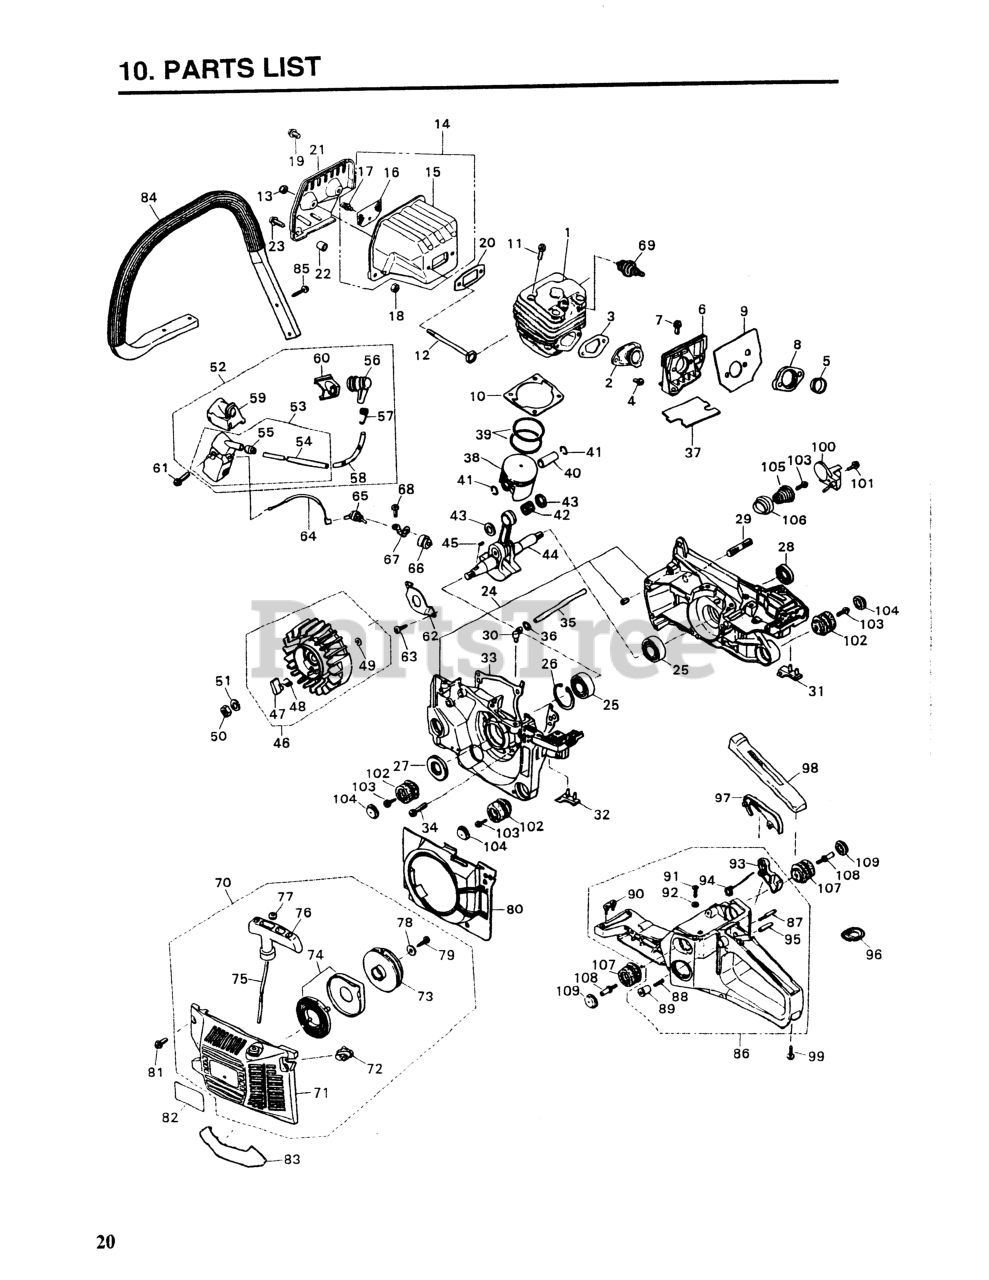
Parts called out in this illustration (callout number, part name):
2	PIPE, INLET
4	SCREW
5	GUIDE
7	SCREW (REPLACES 2616-24320)
12	BOLT
13	NUT, MUFFLER (RPLS 3356-15230
16	ARRESTER, SPARK
18	NUT, M5 X 4
19	SCREW
20	GASKET
21	COVER
26	RING, SNAP, M35 X 1.5
27	SEAL, OIL
28	SEAL, OIL
29	STUD (RPLS 0205-50825)
31	STOPPER, REAR (RPLS 2670-22510
32	STOPPER, REAR
39	RING, PISTON (REPLACES -41210)
40	PIN, PISTON
41	RING, SNAP
42	BEARING
43	WASHER, THRUST
45	KEY
48	SPRING, RETURN
49	RING, SNAP, M4
50	NUT (RPLS -43230)
51	WASHER, M8 x 20
52	COIL (RPLS -71301 & -71300)
53	COIL COMPLETE
54	CORD, HI TENSION
56	CAP, PLUG
57	SPRING PLUG (RPLS 3310-71320)
59	COVER, COIL (RPLS -71300)
63	SCREW, M4 X 10
65	SWITCH (REPLACES 2670-71612)
66	COVER, SWITCH
67	PLATE, EARTH
68	SCREW
74	SPRING COMP
76	KNOB
78	WASHER (USE 181741)
81	SCREW (REPLACES 2616-24320)
83	PROTECTOR
84	HANDLE, LEFT
85	SCREW (USE 848-825-1901)
86	HANDLE ASSY (RPLS -33004)
87	STOPPER
89	KNOB
90	DAMPER (REPLACES 3356-33281)
93	LEVER (RPLS-33310)
94	SPRING
97	ARM (USE -33352)
98	COVER, GRIP
99	SCREW (USE 848-825-1901)
100	CATCHER, CHAIN (RPL 2670-25212
101	SCREW (REPLACES 2616-24320)
102	DAMPER
105	SPRING
106	SPACER
107	DAMPER
109	CAP
